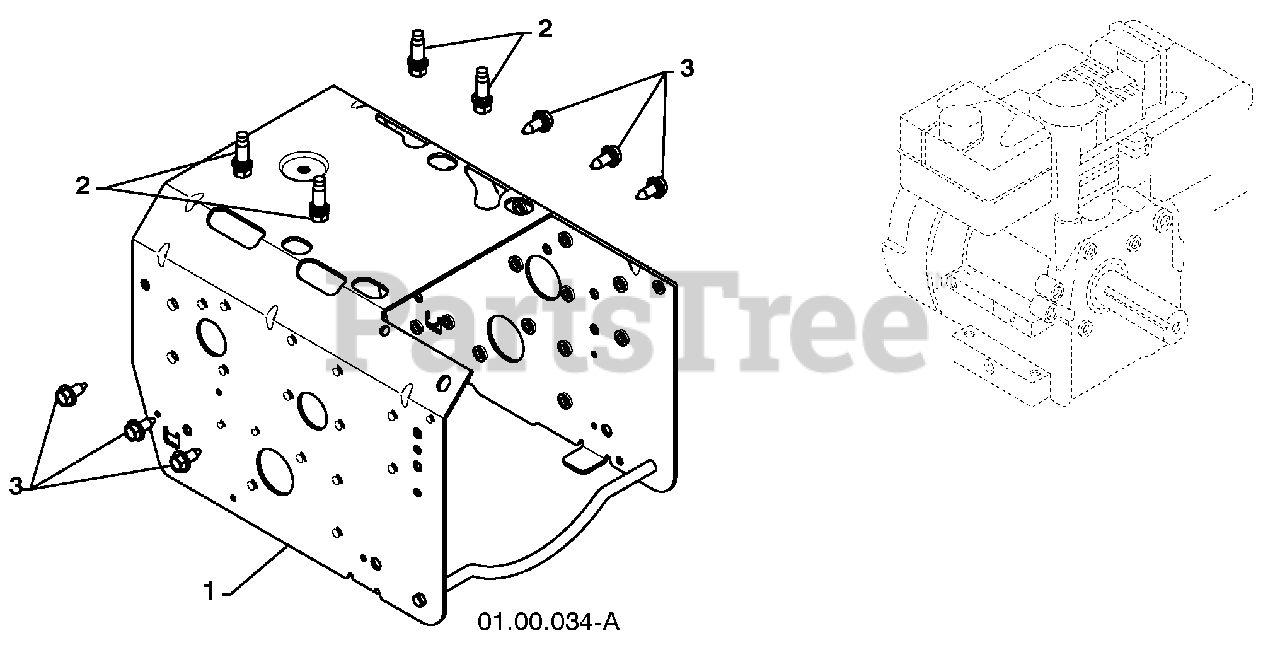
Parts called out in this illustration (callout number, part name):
1	FRAME
2	BOLT 3/8-16
3	SCREW 5/16-18 X .750
